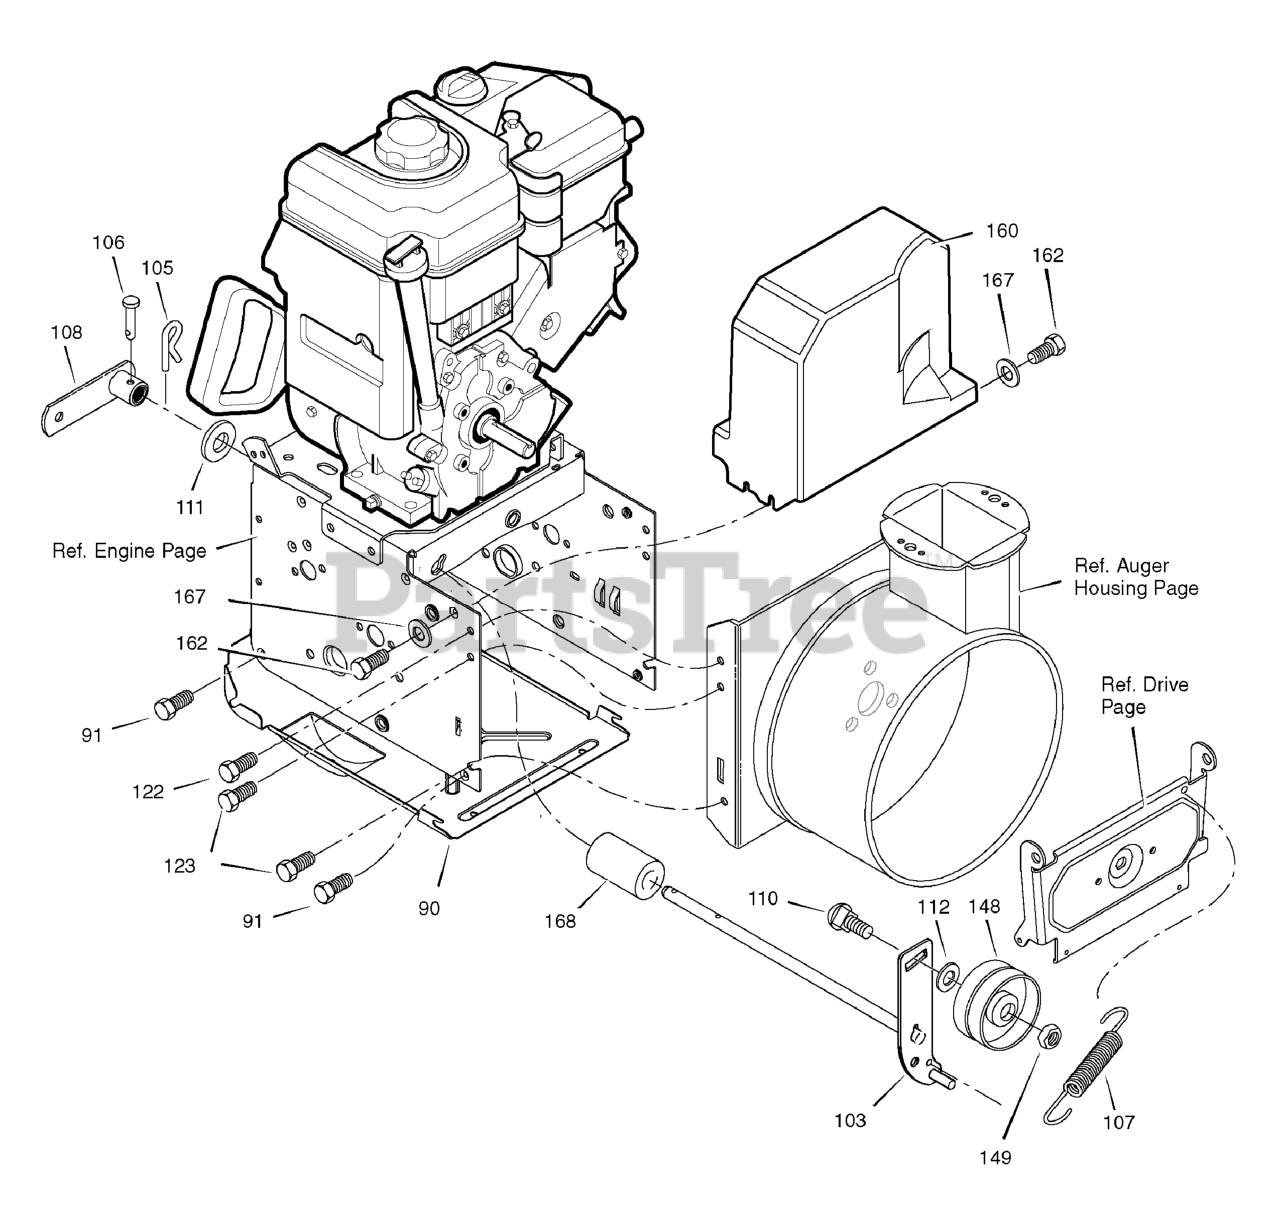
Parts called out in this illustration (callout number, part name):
90	COVER, BOTTOM
91	SCREW, 1/4-20 X 0.63
103	IDLER ASSEMBLY, AUGER
105	PIN, HAIR .38DIA X 1.64LG
106	PIN, CLEVIS 3/16" DIA
107	SPRING, TENSION
108	SPRING ATTACH ASSEMBLY
110	BOLT, 3/8-16 X 1.25 CARRIAGE
111	WASHER, FLAT
122	SCREW, TAP 5/16-18 X 0.50
123	SCREW, TAP 5/16-18 X 0.75
148	PULLEY, IDLER
149	NUT, JAM 3/8-16
160	COVER, BELT
162	SCREW, TAP
167	WASHER, FLAT
168	SPACER, AUGER BRACKET
